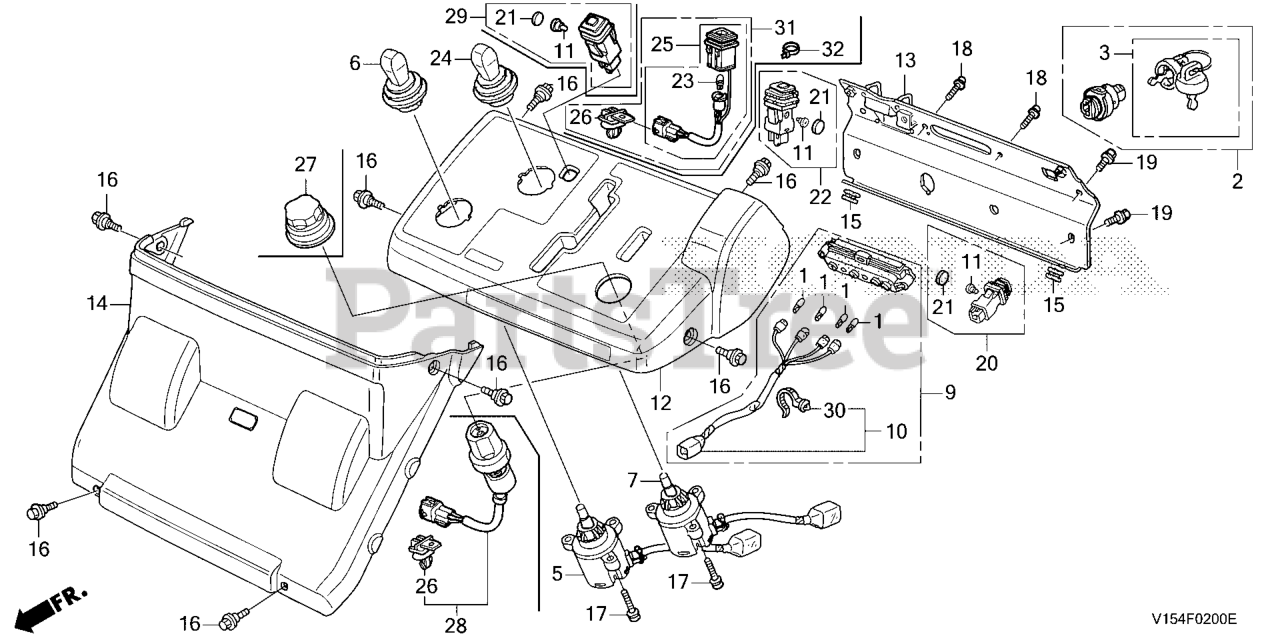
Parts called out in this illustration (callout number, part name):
1	BULB, WEDGE BASE (24V 1.4W)
2	SWITCH ASSY., COMBINATION
3	KEY ASSY., COMBINATION SWITCH
5	SWITCH ASSY., CHUTE CONTROL
6	BOOT, RUBBER (BLACK)
7	SWITCH ASSY., CHUTE CONTROL
9	INDICATOR ASSY., WARNING
11	SOCKET ASSY., LAMP
12	PANEL, CONTROL *NH296* (ALPS GRAY)
13	PANEL, RR.
14	COVER, FR. PANEL *NH296* (ALPS GRAY)
16	BOLT, CONTROL PANEL
17	BOLT-WASHER (5X20)
18	SCREW-WASHER (4X16)
19	BOLT, FLANGE (6X12)
21	CAP, VALVE
23	BULB (28V/2.5W)
24	BOOT, RUBBER (LIGHT GRAY)
26	CLIP, CONNECTOR (DARK GREEN)
27	KNOB, MODE SELECT
28	SWITCH ASSY., MODE SELECT
29	SWITCH ASSY., CLUTCH ON OPERATING
30	BAND, WIRE HARNESS (110MM) (BROWN)
31	SWITCH ASSY.
32	BAND, WIRE HARNESS
